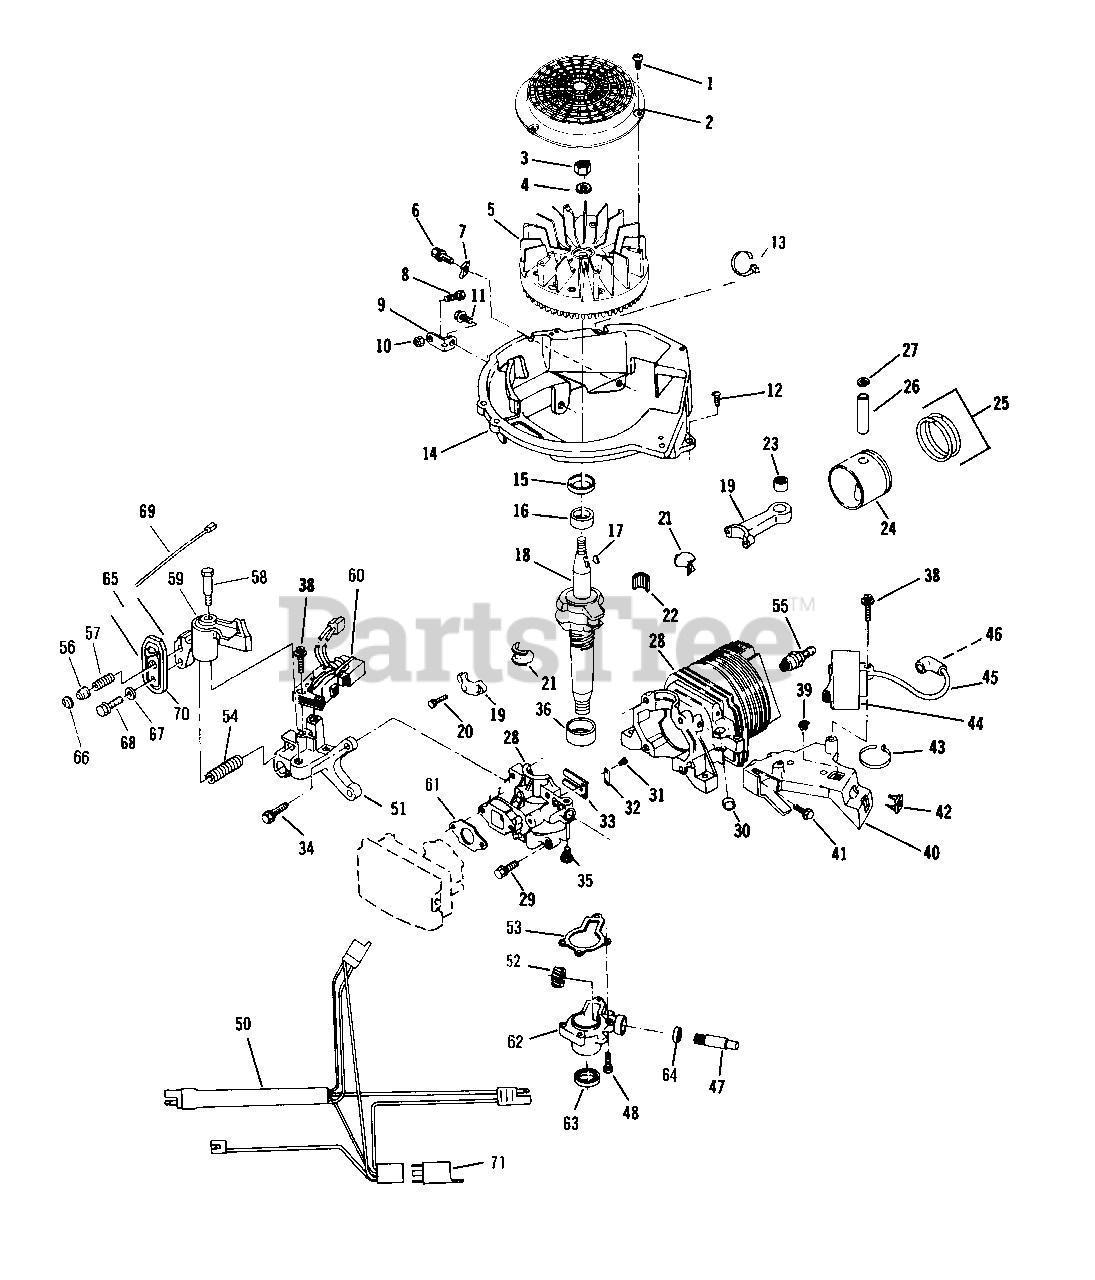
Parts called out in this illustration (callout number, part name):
1	Screw-Flywheel
2	Screen-Flywheel
3	Nut-Flywheel
4	Lockwasher
5	Flywheel
6	Screw
7	"J" Clip
8	Bolt-Brace-Alternator Bracket
9	Brace-Alternator Bracket
10	Locknut-Brace-Alternator Brkt.
11	Screw
12	Screw-Shroud Base to C.D. Brkt.
13	Tie Strap
14	Base-Shroud
15	Oil Seal-Upper
16	Bearing-Upper
17	Key-Flywheel
18	Crankshaft
19	Connecting Rod Assembly
20	Screw-Cap
21	Liner Split
22	Needle Bearing Set
23	Bearing Assembly
24	Piston and Ring Set
25	Ring Set
26	Wrist Pin
27	Retaining Ring
28	Cylinder and Crk'c Cover Asy
29	Screw-Cover to Crankcase
30	Plug
31	Screw-Reed to Crk'c Cover
32	Plate-Reed Hold Down
33	Reed
34	Screw-Alt. and Brake Mtg. Brkt
35	Set Screw-Starter Assembly
36	Bearing-Lower
38	Screw-C.D. & Alternator Mtg.
38	Screw-C.D. Mounting
39	Grommet-C.D. Bracket
40	Bracket-Ignition Mounting
41	Screw
42	Grommet-C.D. Bracket
43	Tie Strap
44	C.D. Ignition Module and Lead Asy
45	High Tension Lead and Cvr. Asy
46	Spring Terminal
47	Driveshaft
48	Screw-Gear Box
50	Wire Harness Assembly
51	Bracket-Alternator and Brake
51	Bracket-Brake
52	Gear
53	Gasket-Gear Box
54	Spring-Brake
55	Spark Plug
56	Actuator-Brake Lever
57	Spring-Cable Retainer
58	Bolt-Shoulder
59	Brake Assembly
60	Alternator Assembly
61	Gasket-Carb. to Crankcase Cvr.
62	Gear Box Assembly
63	Oil Seal Crankshaft
64	Seal-Driveshaft
65	Switch Assembly
66	Retainer
67	Washer
68	Screw
69	Lead Assembly
70	Case Assembly Only
71	Relay
